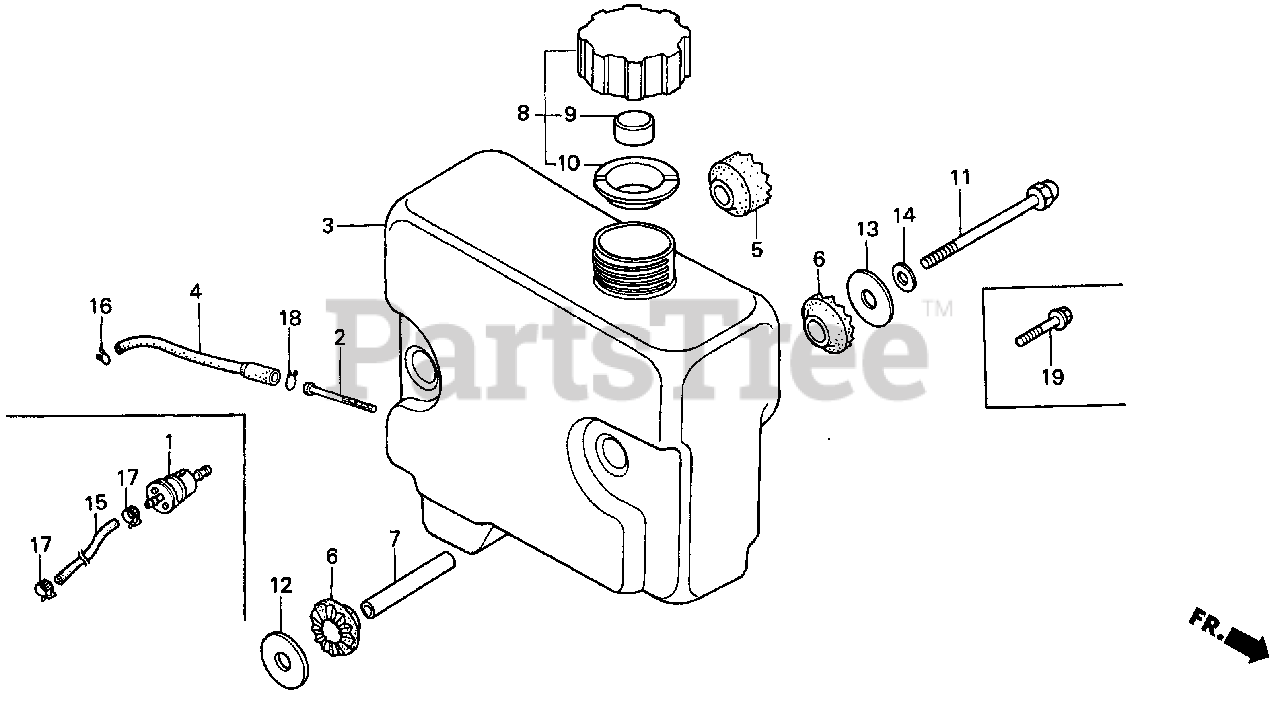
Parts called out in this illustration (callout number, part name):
1	FILTER, FUEL
15	BULK HOSE, FUEL (4.5X3000) (4.5X360)
17	CLIP, TUBE (D8.5)
19	BOLT, FLANGE (8X16)
